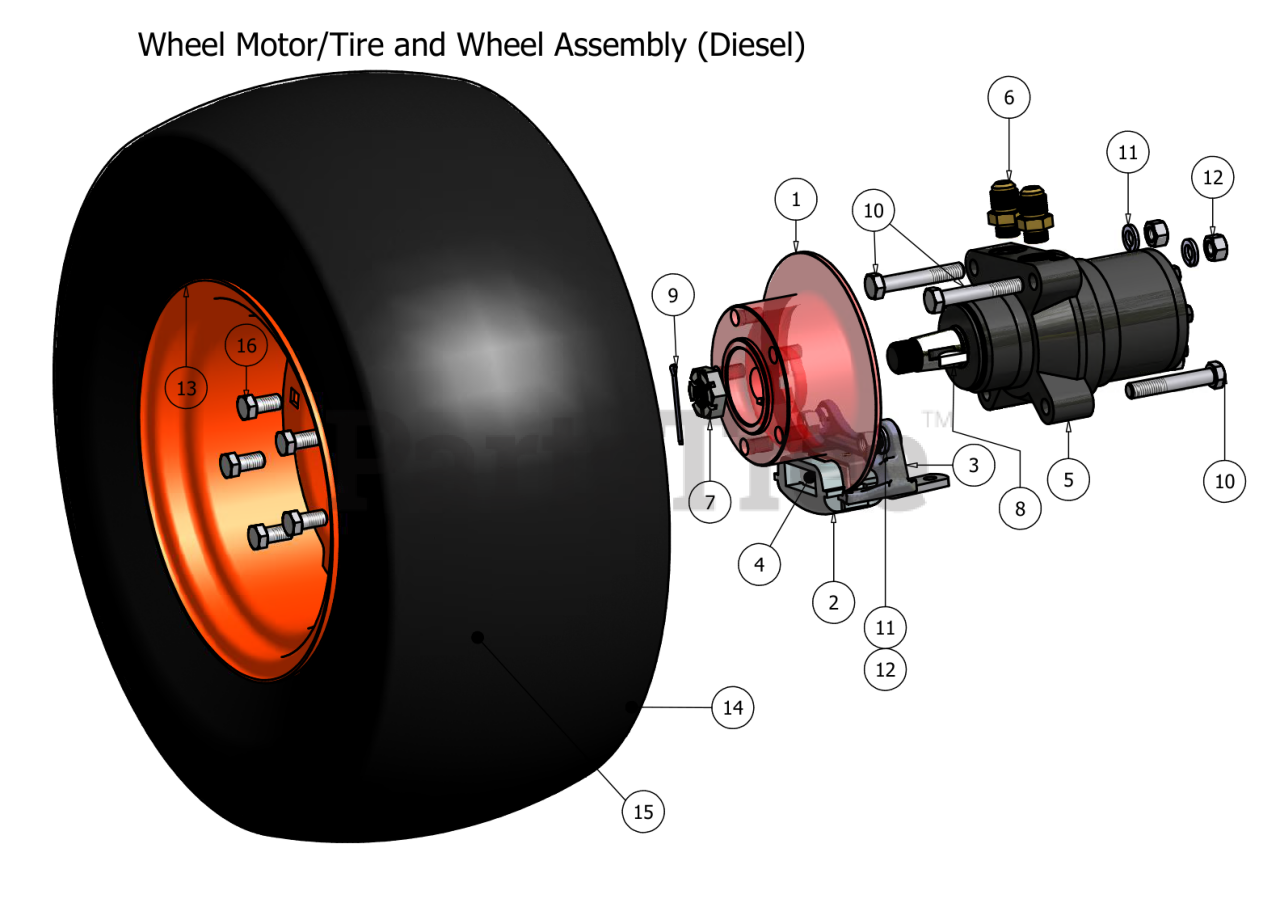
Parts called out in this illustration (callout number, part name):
1	Brake Disc
2	Right Brake Assmebly/ Left
2	Left Brake Assembly
3	Brake Casting
4	Brake Pads
5	Right Wheel Motor
5	Left Wheel Motor
6	Hydraulic Fitting
7	Castle Nut
8	Woodruff Key
9	1/8" x 2 1/4" Cotter #8
10	1/2" x 3" Hex Bolt
11	1/2" Lock Washer
12	1/2" Hex Nut
13	12" Rim -60" &72"Cut
14	24x12-12 Tire -60"&72" Cut
15	24" Tire and Wheel Assembly
16	1/2" x 1" Lug Bolt (Fine Thread)
17	12" Rim -48" & 52" Cut
18	23x10.50-12 Tire - 48" & 52" Cut
19	23x10.50-12 Tire and Wheel Assembly
